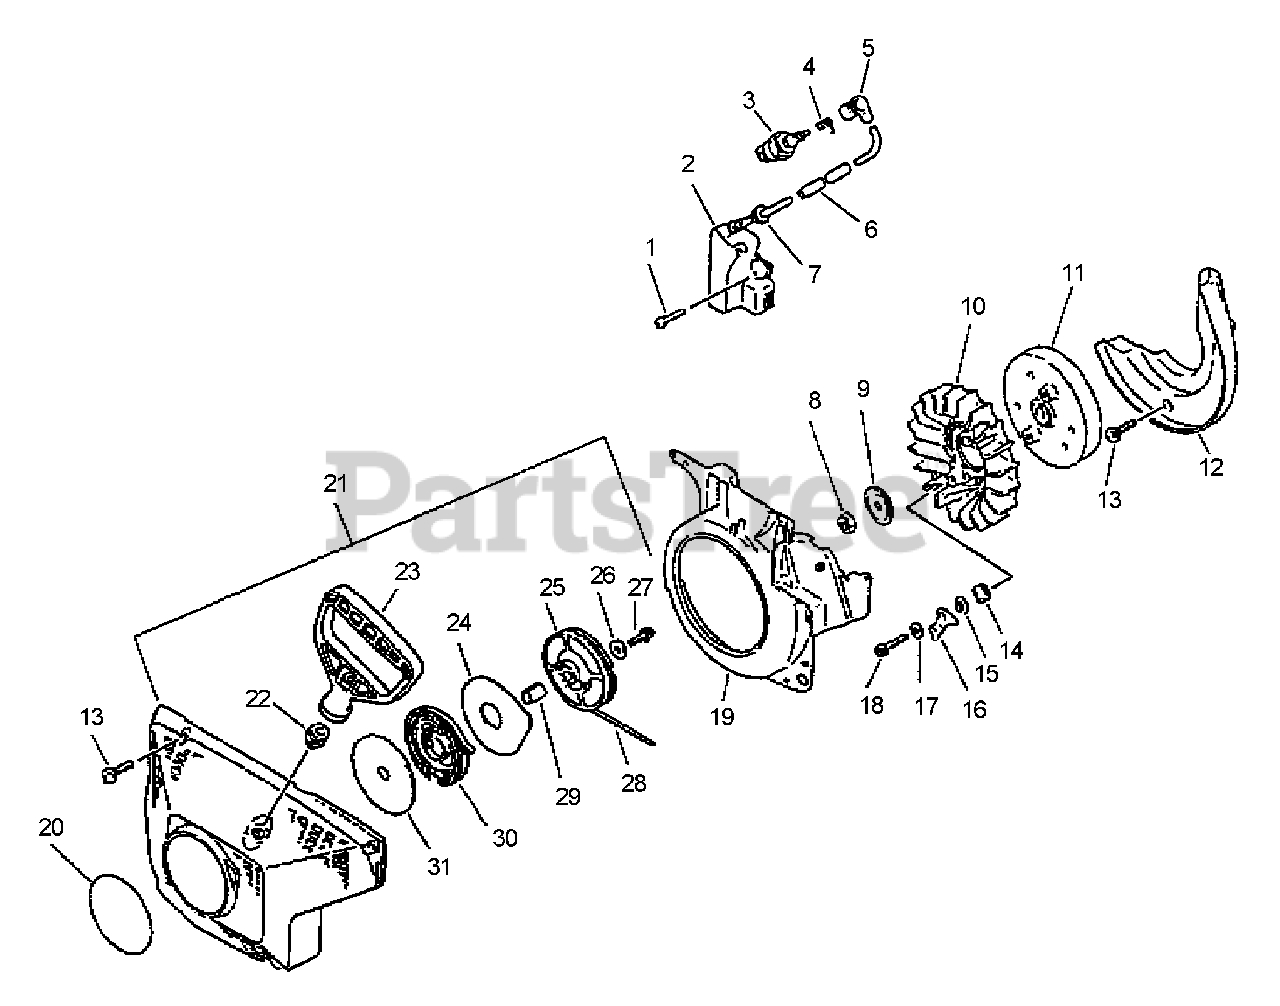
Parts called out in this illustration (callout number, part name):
1	SCREW - 4X20
2	COIL, IGNITION
3	SPARK PLUG -- CJ-6Y
4	TERMINAL, SPARK PLUG CAP
5	CAP, SPARK PLUG
8	NUT - FLANGE
9	WASHER - CUP
10	FAN
11	FLYWHEEL
12	SHIELD, FAN
13	SCREW - 5X20
14	SPRING, RETURN
16	PAWL, STARTER
17	WASHER - 5
18	SCREW - 5X30
19	SHIELD, FAN
20	LABEL - ECHO
21	STARTER ASSY
22	GUIDE, ROPE
23	GRIP, STARTER
24	PLATE, STARTER
25	REEL, ROPE
26	WASHER - 5
27	SCREW - 5X14
28	ROPE, STARTER - 4X900
30	SPRING, REWIND
31	PLATE, STARTER
